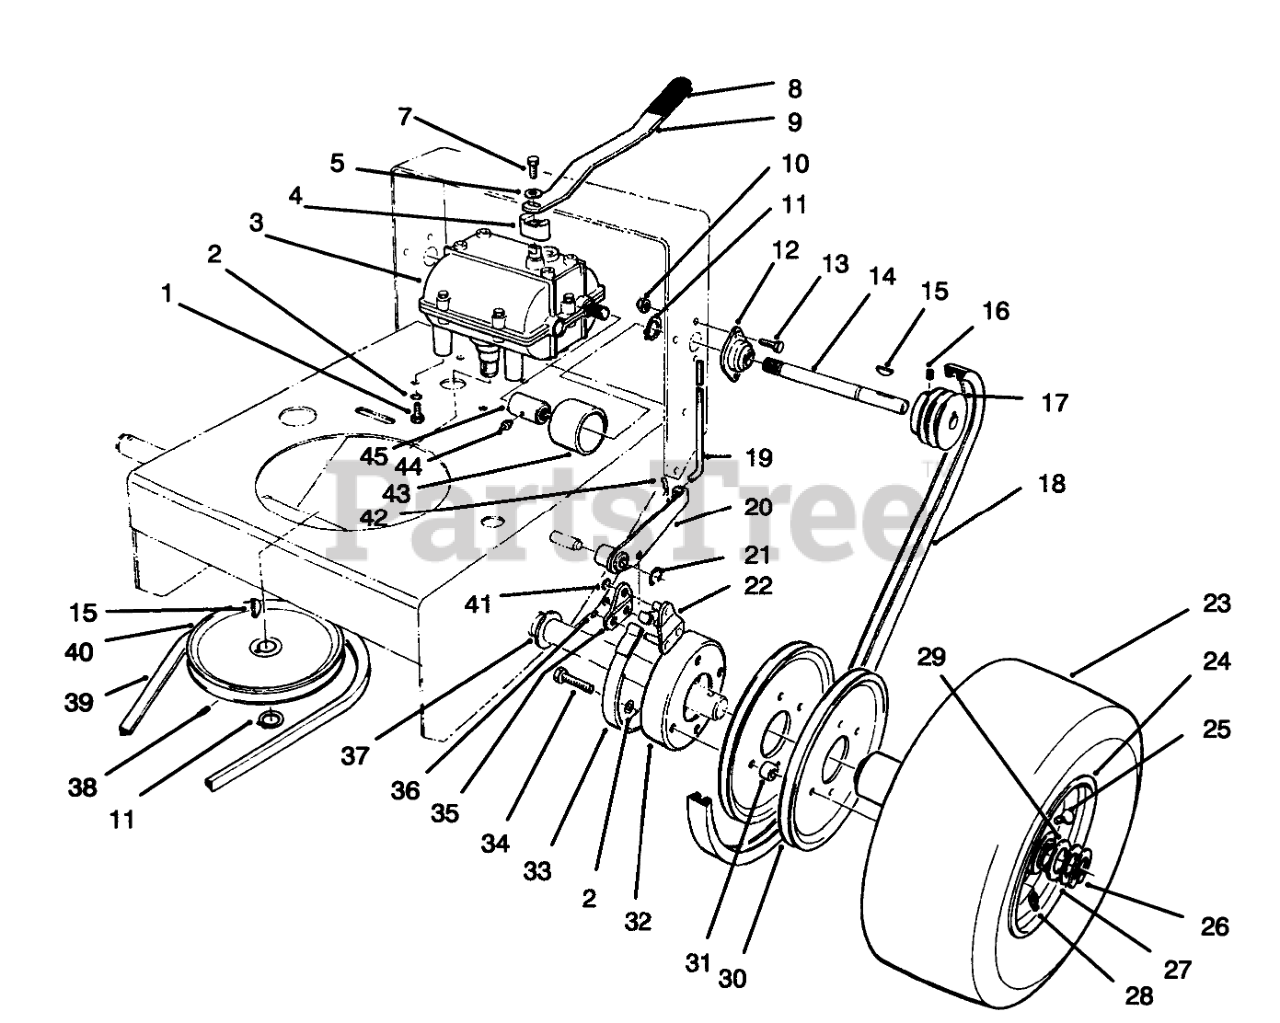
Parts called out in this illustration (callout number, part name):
1	SCREW-HH
2	WASHER-LOCK
3	TRANSMISSION
4	MOUNT-LEVER, SHIFT
5	SPACER
7	SCREW-HH
9	Lever-Shift
10	NUT-LOCK, NI
11	RING-SNAP, EXTERNAL
12	BEARING-EXTERNAL SHAFT
13	SCREW-HH
14	SHAFT-EXTENSION, RH
15	KEY-WOODRUFF
16	SCREW-SET, HS
17	Pulley-Drive
18	V-BELT
19	ROD-BRAKE
20	Arm-Brake LH
21	RING-RETAINING
22	LINK-Brake
23	TIRE-FRONT
24	WHEEL ASM
25	STEM-VALVE
26	RING-RETAINING
27	BEARING-BALL
28	FITTING-GREASE
29	WASHER-THRUST
30	Pulley-Wheel
31	SPACER-PULLEY
32	Drum-Brake
33	BAND-BRAKE
34	SCREW-HH
35	Plate-Link
36	RING-RETAINING
37	WASHER-WHEEL
38	SCREW-SET
39	V-BELT
40	PULLEY-DRIVEN
41	RING-RETAINING, EXTERNAL
42	PIN-COTTER
43	GUARD-COUPLER
44	FITTING-GREASE
45	COUPLER
